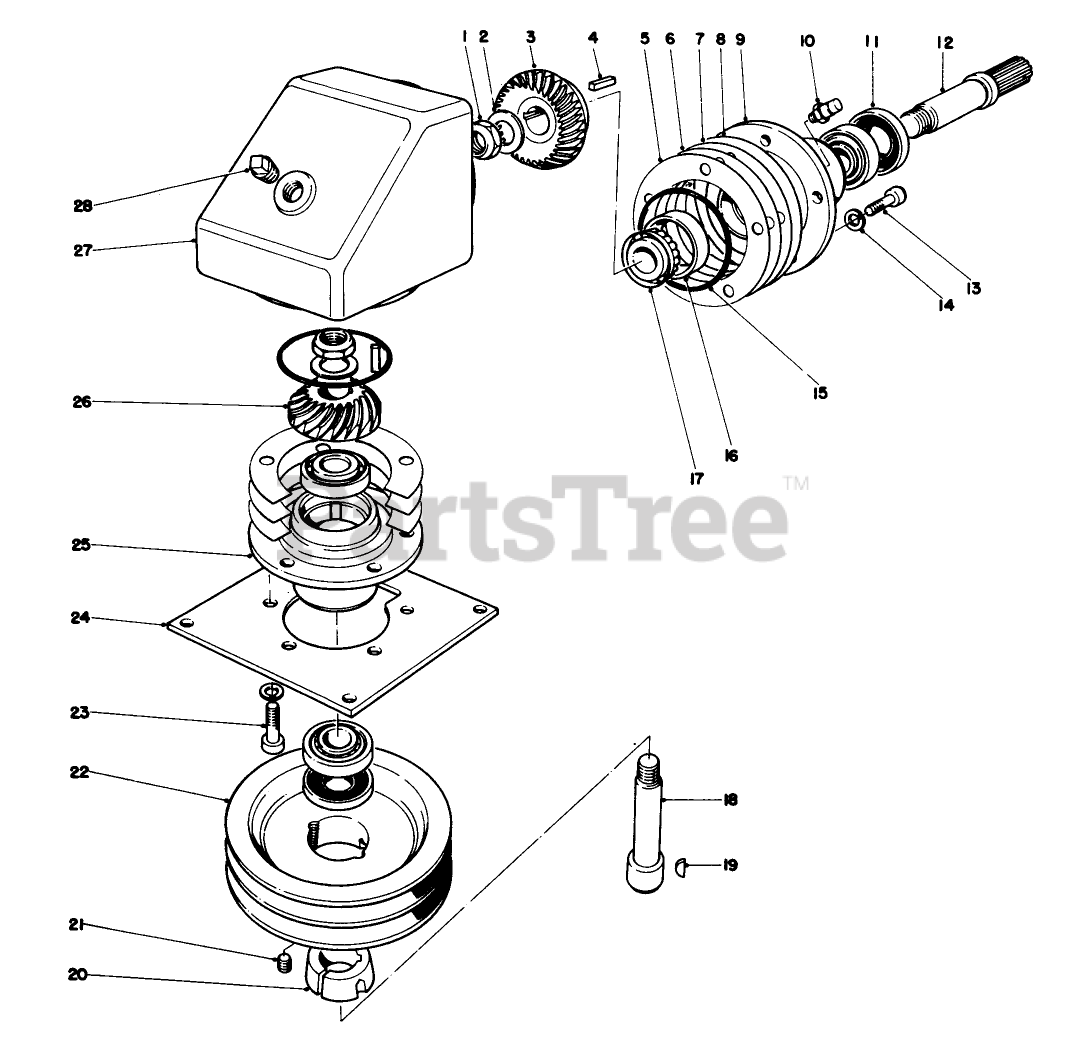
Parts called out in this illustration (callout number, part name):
1	NUT-LOCK, NI
2	THRUST WASHER
4	KEY-SQUARE
5	.002 SHIM (RED)
6	.005 SHIM (BLUE)
7	.015 SHIM (PINK)
9	INPUT BRG HSG
11	OIL SEAL
12	INPUT SHAFT
13	SCREW-HSH
14	WASHER-LOCK
15	O-RING
16	BEARING-CUP
17	CONE-BEARING
18	OUTPUT SHAFT
19	KEY-WOODRUFF
20	Bushing-Taper Lock (Incl. Ref. #2)
21	SCREW-SET
22	PULLEY-DECK
23	SCREW-HSH
24	GEAR BOX MTG PLT R
25	OUTPUT BRG HSG
26	PINION
27	GEAR BOX
28	3/8-18 SQ HD PLUG/MAG
